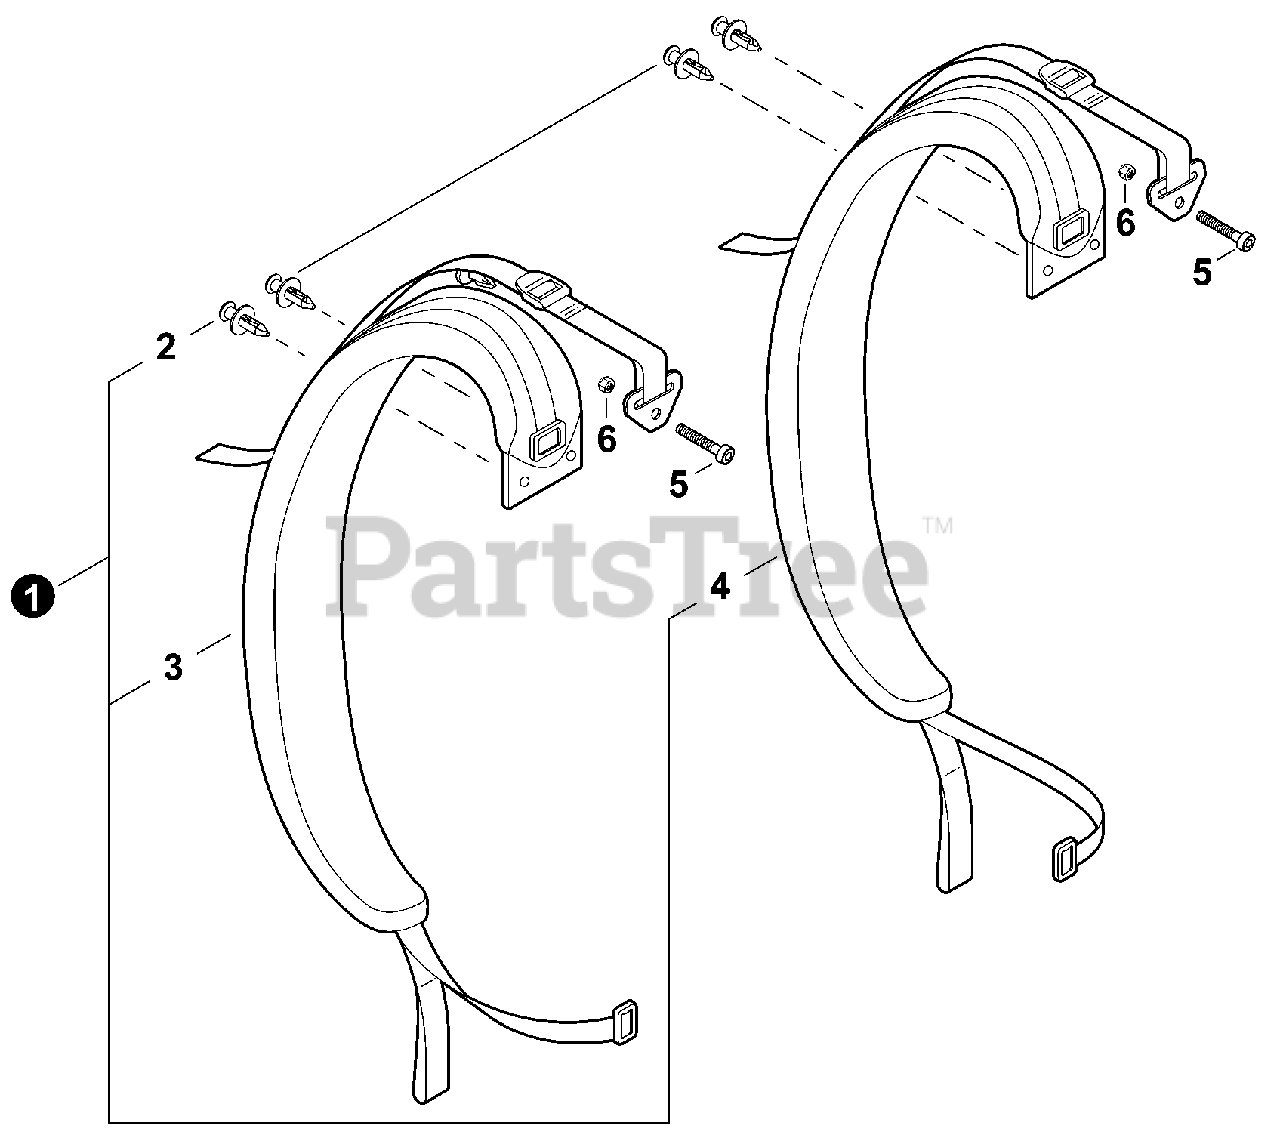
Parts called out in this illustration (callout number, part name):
1	HARNESS KIT
1	BULK PIPE - 3×5 MM BLACK (4 PIECES×2 M)
1	BULK STARTER ROPE - Ø 2.3 MM×61 M
2	BULK PIPE - 3×6 MM BLACK (4 PIECES×2 M)
2	BULK STARTER ROPE - Ø 3.0 MM×61 M
3	HARNESS ASSY, LEFT
3	BULK PIPE - 3×7 MM BLACK (4 PIECES×2 M)
3	BULK STARTER ROPE - Ø 3.5 MM×61 M
4	HARNESS ASSY, RIGHT
4	BULK PIPE - 3×6 MM CLEAR (4 PIECES×2 M)
4	BULK STARTER ROPE - Ø 4.0 MM×61 M
5	BOLT, TORX 5×30
5	BULK PIPE - 2×4 MM CLEAR (4 PIECES×2 M)
5	BULK STARTER ROPE - Ø 4.4 MM×61 M
6	NUT, LOCK M5
6	BULK STARTER ROPE - Ø 4.8 MM×61 M
